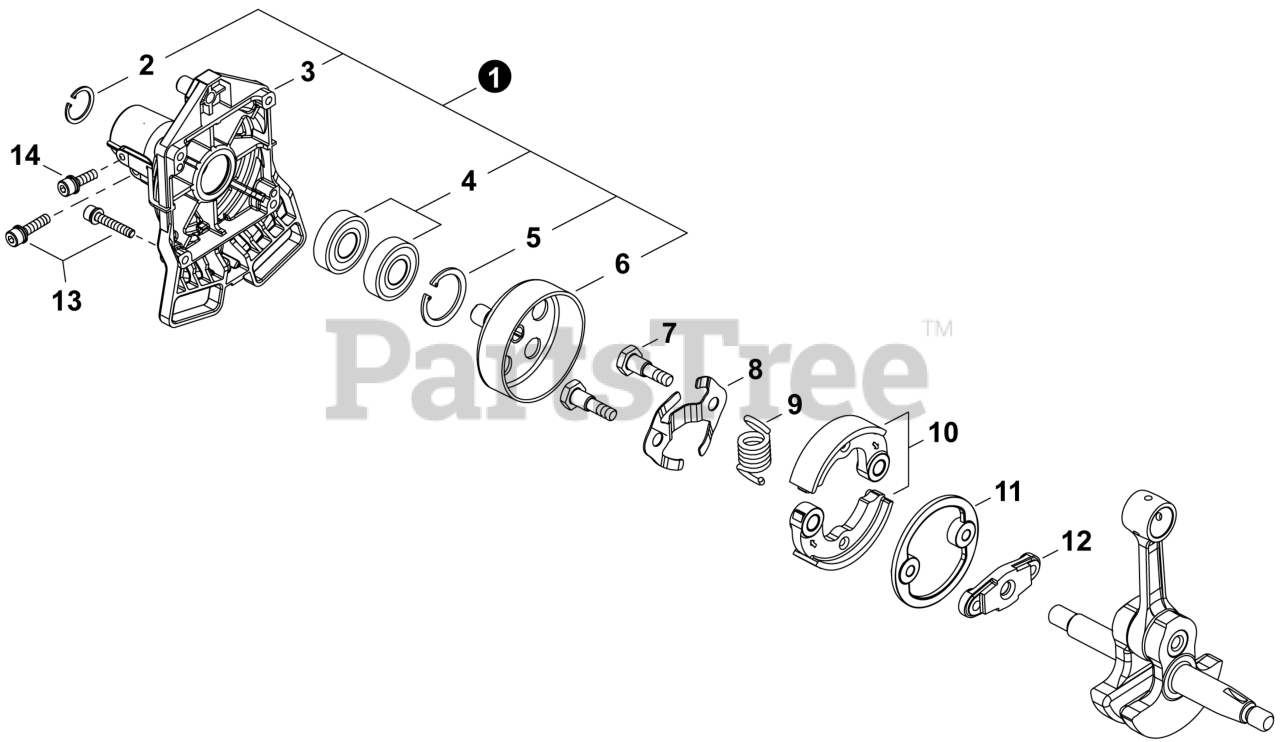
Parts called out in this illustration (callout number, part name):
1	COVER ASSY, FAN
2	RING, SNAP 12
3	CASE, CLUTCH
4	BEARING, BALL
5	RING, SNAP 28
6	DRUM, CLUTCH
7	BOLT, CLUTCH
8	SPRING, FLAT
9	SPRING, CLUTCH
10	CLUTCH SHOE SET
12	HUB, CLUTCH
13	BOLT, TORX 5x20
14	BOLT, TORX 5x10
